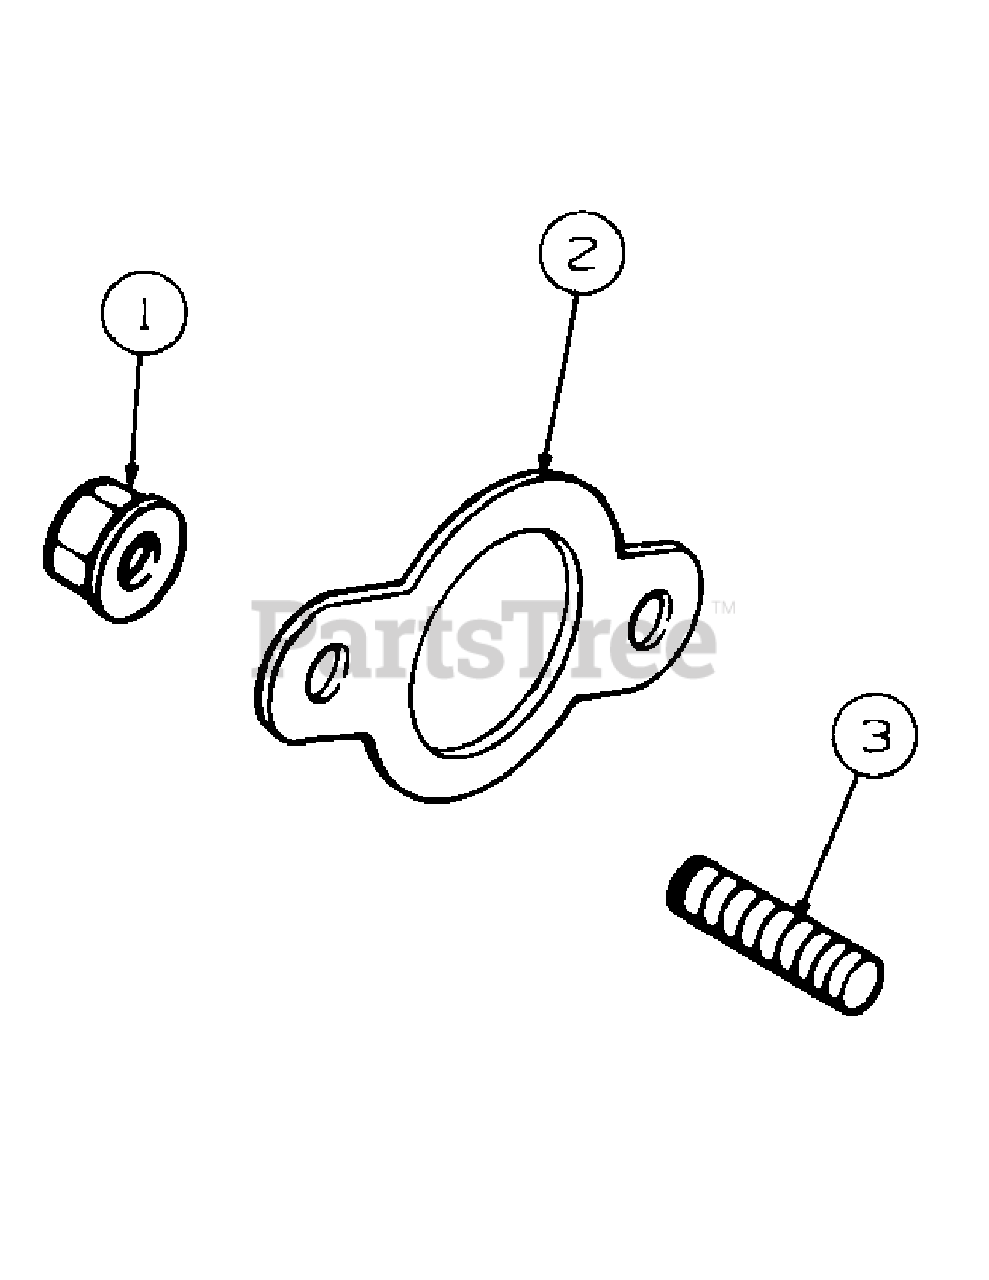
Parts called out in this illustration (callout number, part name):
1	Nut, Muffler Mounting, M8 x 1.25
2	Gasket, Exhaust
3	Stud, Exhaust, M8 x 1.25 x 33
